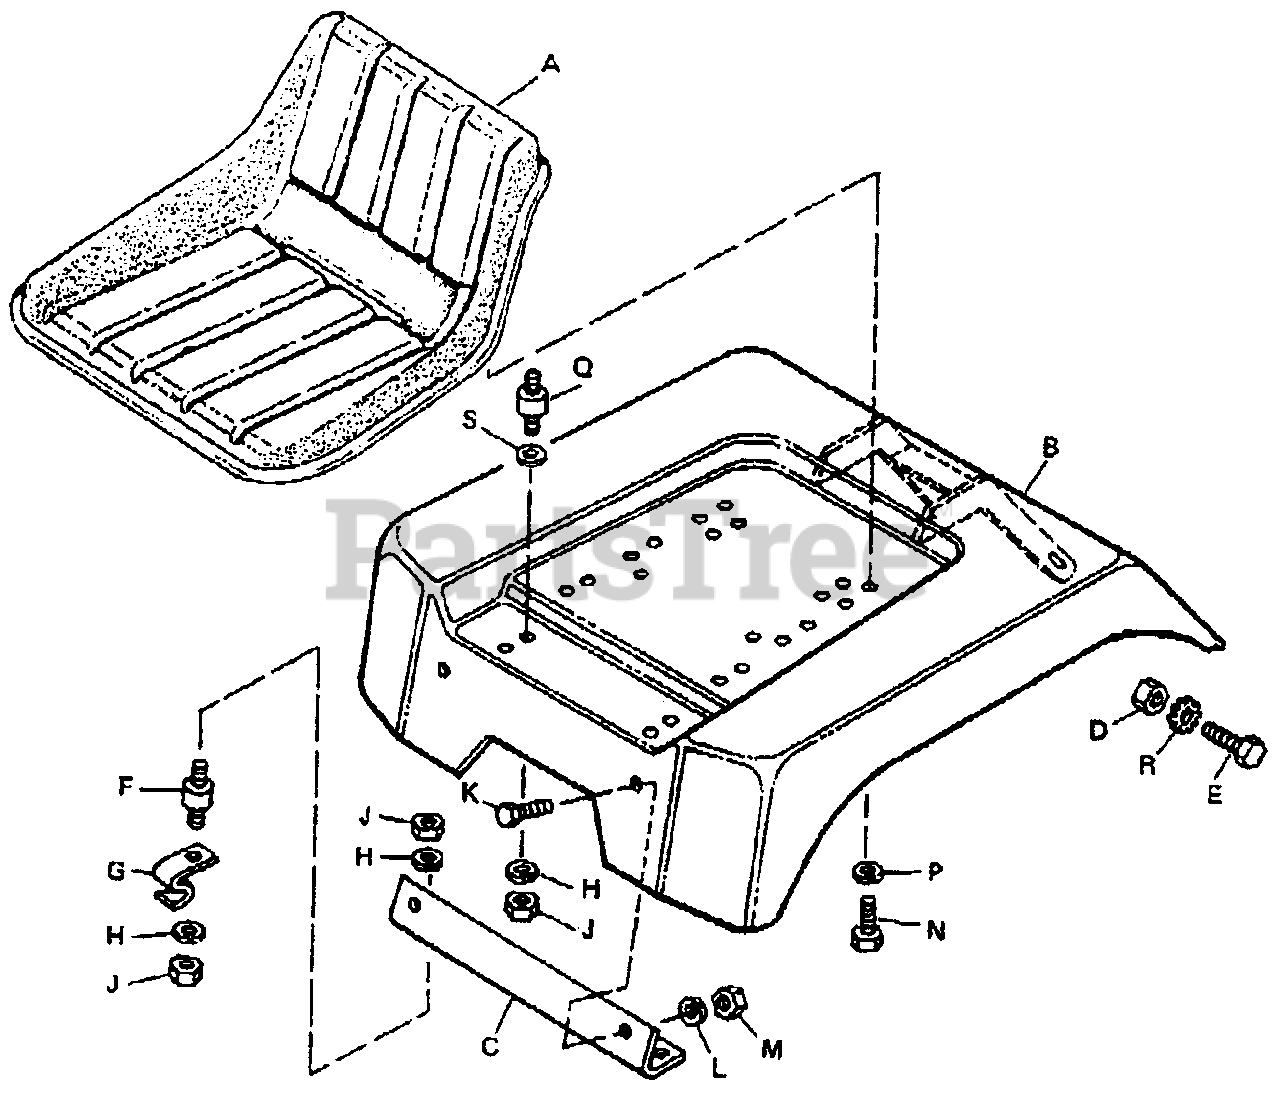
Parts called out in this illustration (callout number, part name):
B	Seat Deck Assy.
C	Seat Deck Bracket, Front
D	Hex Locknut, Full, 3/8"-16
E	Hex Head Capscrew, 3/8"-16 x 1-1/4"
F	Cushion Connector, Front
G	Spring Clip
H	Lock Washer, 5/16"
J	Hex Nut, Full, 5/16"-18
K	Hex Head Capscrew, 5/16"-18 x 5/8"
L	Lockwasher, 5/16"
M	Hex Nut, Full, 5/16"-18
N	Hex Head Capscrew, 5/16"-18 x 5/8"
P	Lockwasher, 5/16"
Q	Cushion Connector, Front
R	Lock Washer
